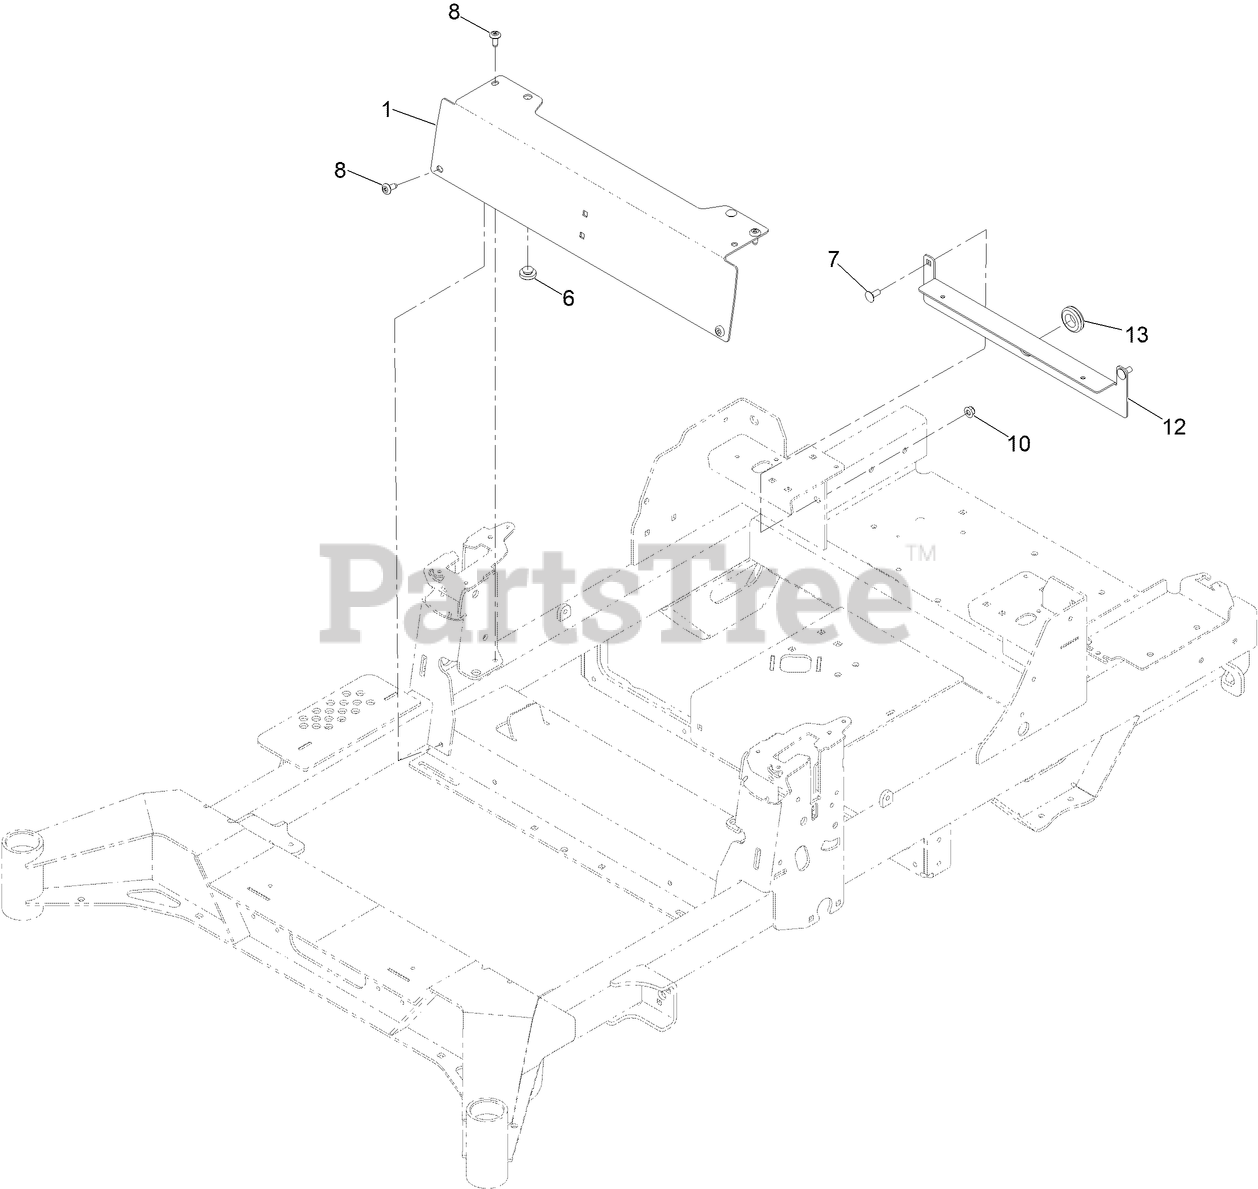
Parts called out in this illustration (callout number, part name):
1	PLATE-BADGE, FRONT [BLACK]
6	BUMPER-SEAT
7	SCREW-CARR
10	NUT-HF, NI
12	BRACKET-FIREWALL
13	GROMMET
